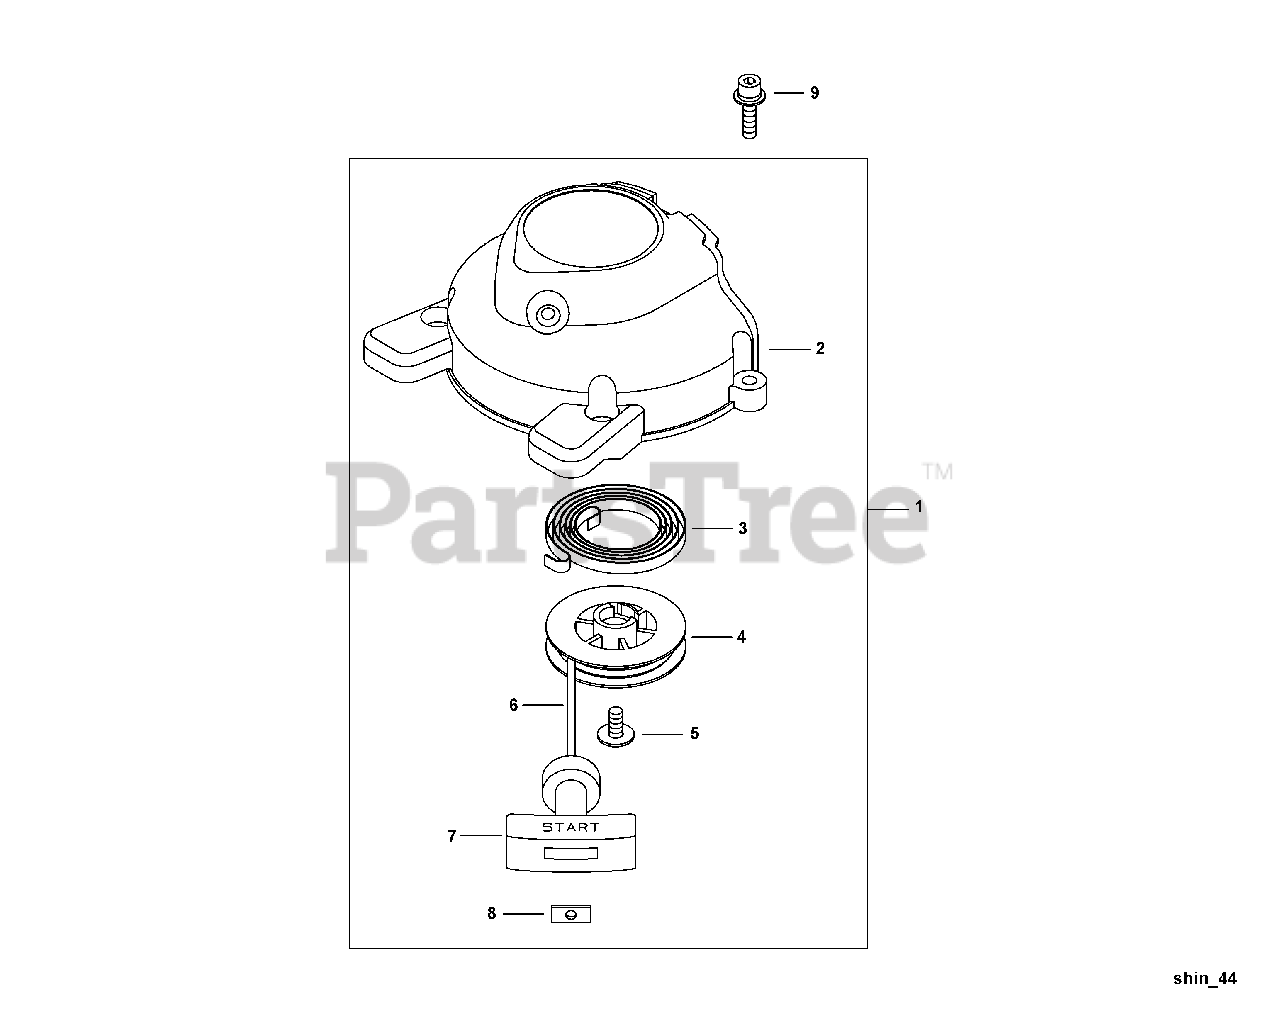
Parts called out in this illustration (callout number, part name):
1	STARTER ASSY, RECOIL
2	CASE, RECOIL STARTER
3	SPRING, RECOIL
4	REEL, ROPE
5	SCREW 5
6	ROPE, STARTER
7	GRIP, STARTER
8	RETAINER, ROPE
9	BOLT, ADHESIVE M5×20
